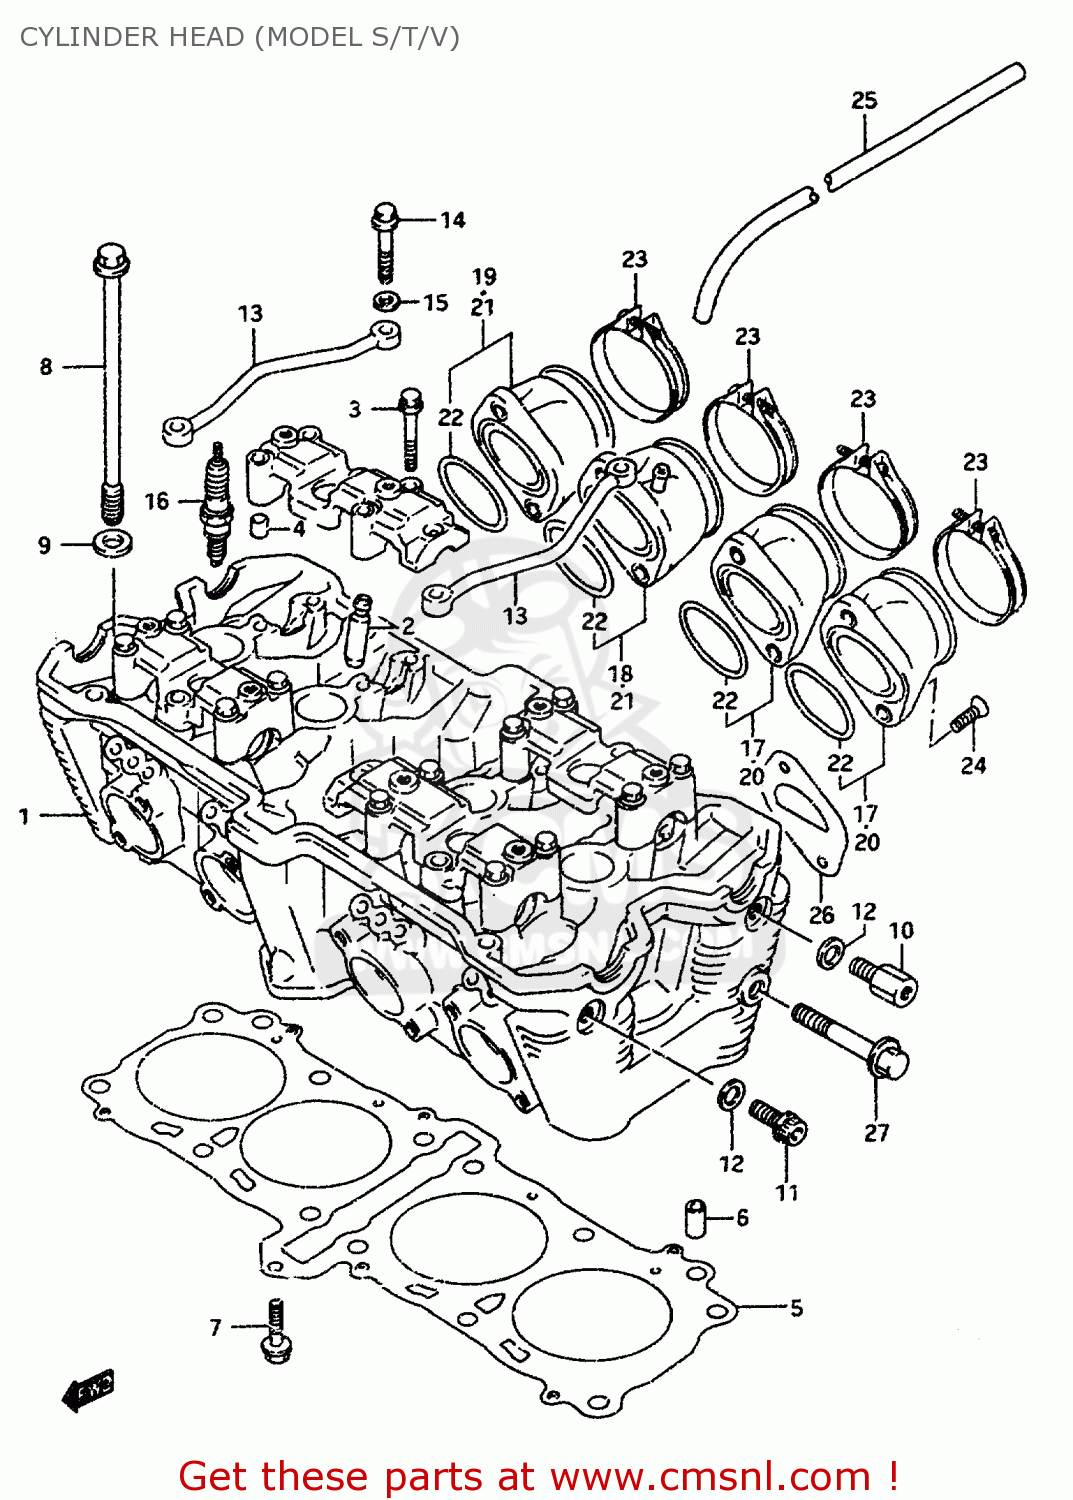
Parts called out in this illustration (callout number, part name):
1	HEAD ASSEMBLY,CYLINDER
2	GUIDE,VALVE
3	BOLT(6X45)
4	PIN(6.2X8X11)
5	GASKET,CYLINDER HEAD
6	PIN
7	BOLT
8	BOLT 10X175
9	WASHER(10.5X19X2)
10	BOLT
11	BOLT
12	GASKET(8.2X14X1).6 (NAS)
13	PIPE,CYLINDER HEAD OIL
14	BOLT(6X39)
15	WASHER
16	PLUG,SPARK(CR8E)
17	PIPE ASSY,INTAKE NO.1
18	PIPE ASSY,INTAKE NO.3
19	PIPE ASSY,INTAKE NO.4
20	PIPE ASSY,INTAKE NO.1
21	PIPE ASSY,INTAKE NO.2
22	O RING(D:2.4,ID:47X42)
23	CLAMP
24	SCREW
25	HOSE,VACUUM
26	PLATE, INTAKE
27	BOLT
